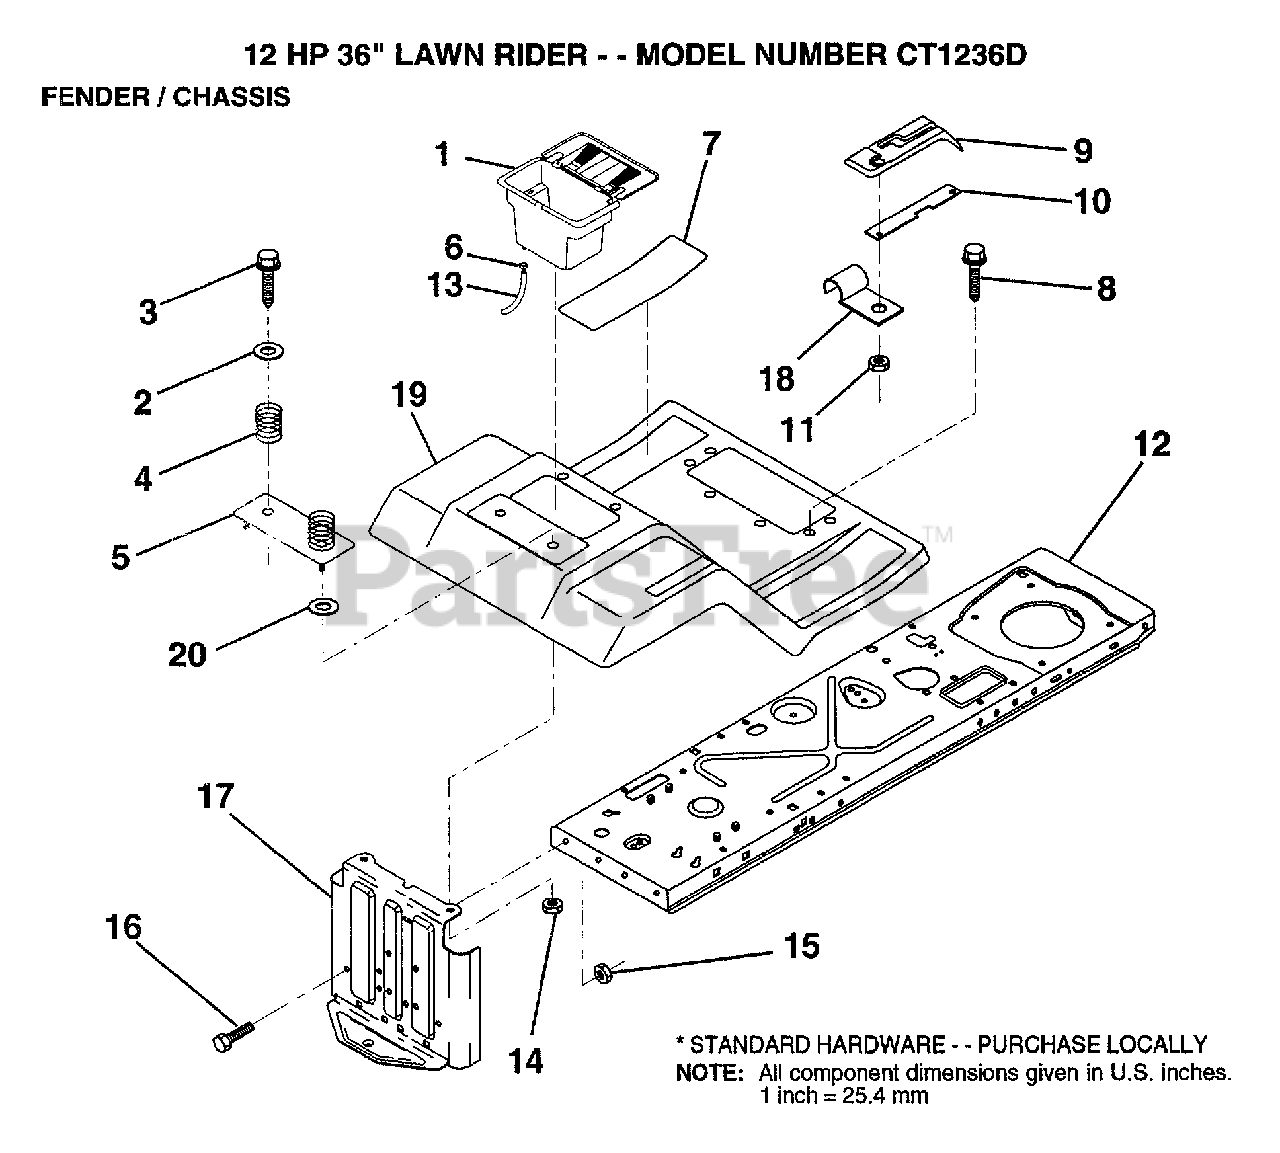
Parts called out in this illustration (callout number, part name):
2	WASHER
3	SCREW
4	SPRING COMPRESSIO
5	"PLATE, BATTERY"
6	HOSE CLAMP T
7	PAD FOOTREST
8	SCREW
10	"SHIFT LOCK, BAR"
11	NUT
12	FRAME ASS'Y
14	NUT
16	BOLT
17	DRAWBAR
18	"CLIP,INSULATOR"
